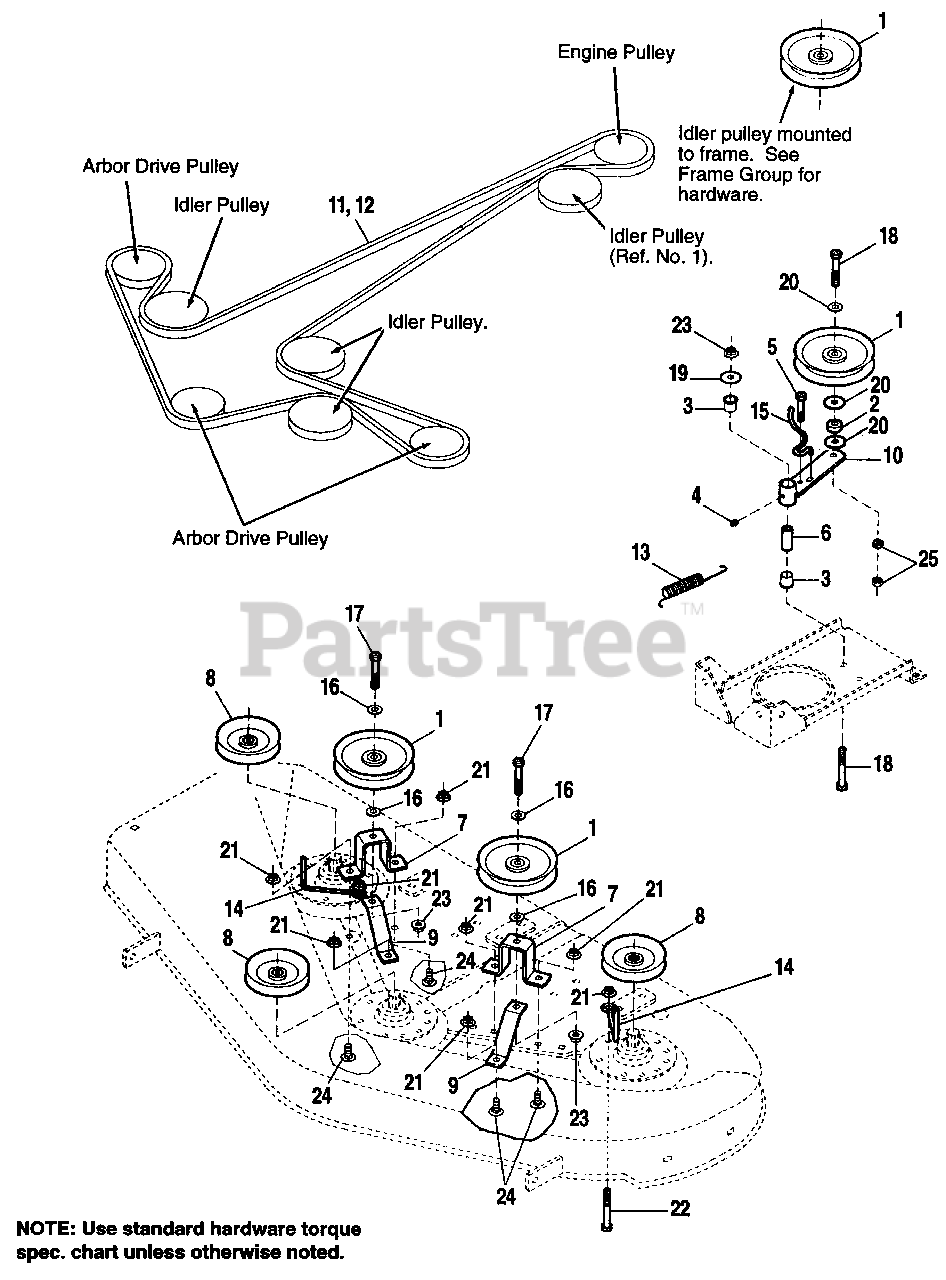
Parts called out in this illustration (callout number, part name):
1	PULLEY ASSY.
4	FITTING, Grease
5	SCREW, Taptite, 5/16-18 X 3/4
7	SUPPORT, Idler
8	PULLEY ASSY., Arbor
10	ARM ASSY., Clutch
11	BELT, Drive, 42"
12	BELT, Drive, 48"
15	STOP, Belt
16	WASHER, 3/8
17	CAPSCREW, Hex, 3/8-16 x 1-3/4
18	CAPSCREW, 3/8-16 X 2-1/4
19	WASHER, 3/8
20	WASHER, 5/16
21	NUT, Flange, Whizlock, 5/16-18
22	CAPSCREW, Taptite, 5/16-18 x 1-1/4
23	NUT, Hex, Whizlock, 3/8-16
24	CARRIAGE BOLT, 5/16-18 x 3/4
25	NUT, Jam Lock, 3/8-16
